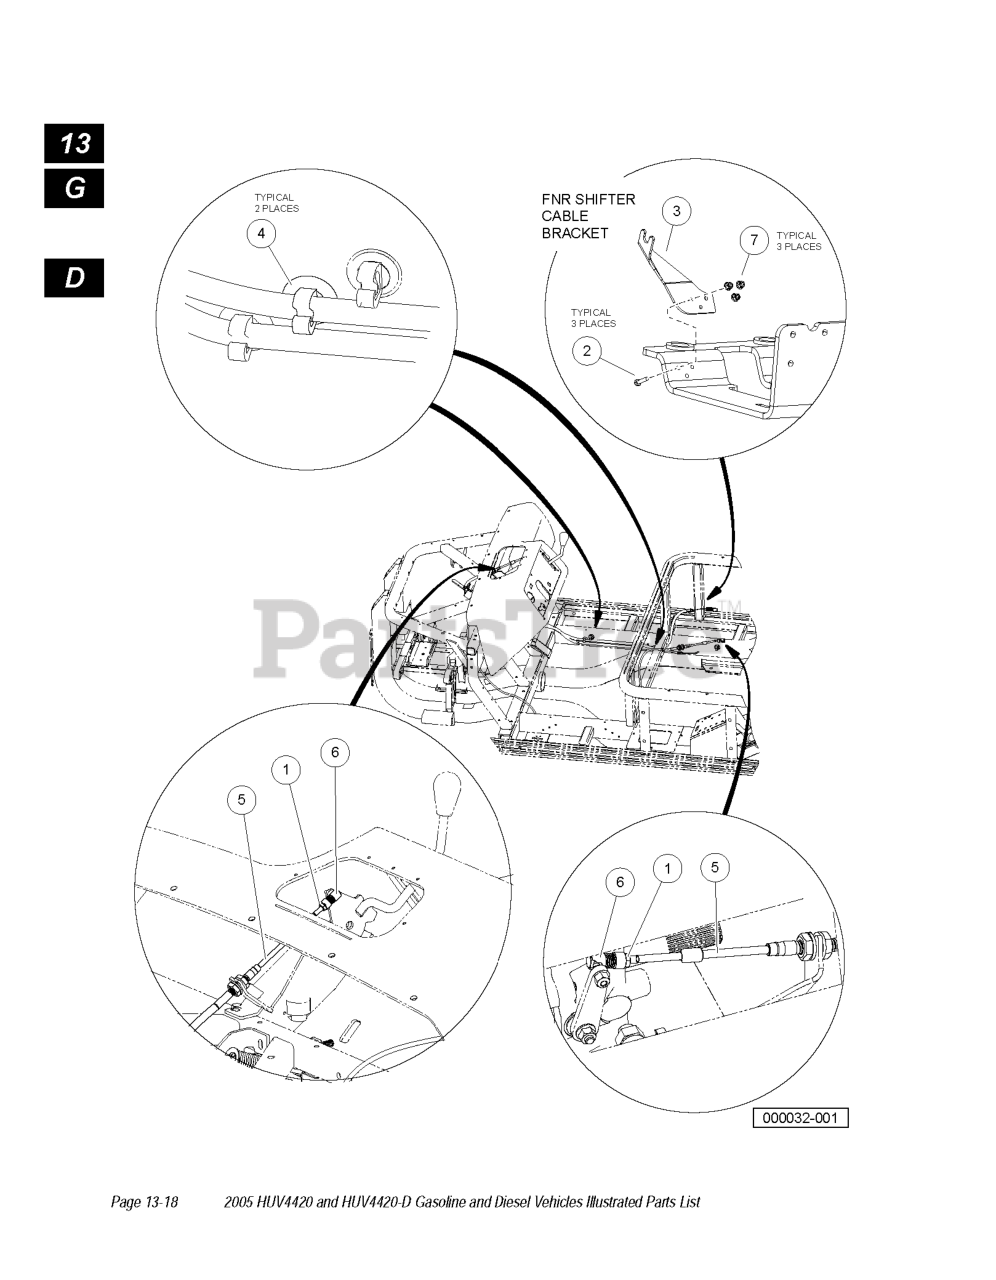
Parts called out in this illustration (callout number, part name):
3	BRACKET, FNR TRANS CABLE
4	CLIP, BRAKE LINE
5	CABLE, TRANSMISSION SHIFT, AWD
6	JOINT, BALL, .346 DIA
7	NUT FLG, M6 X 1.0 NYLON
